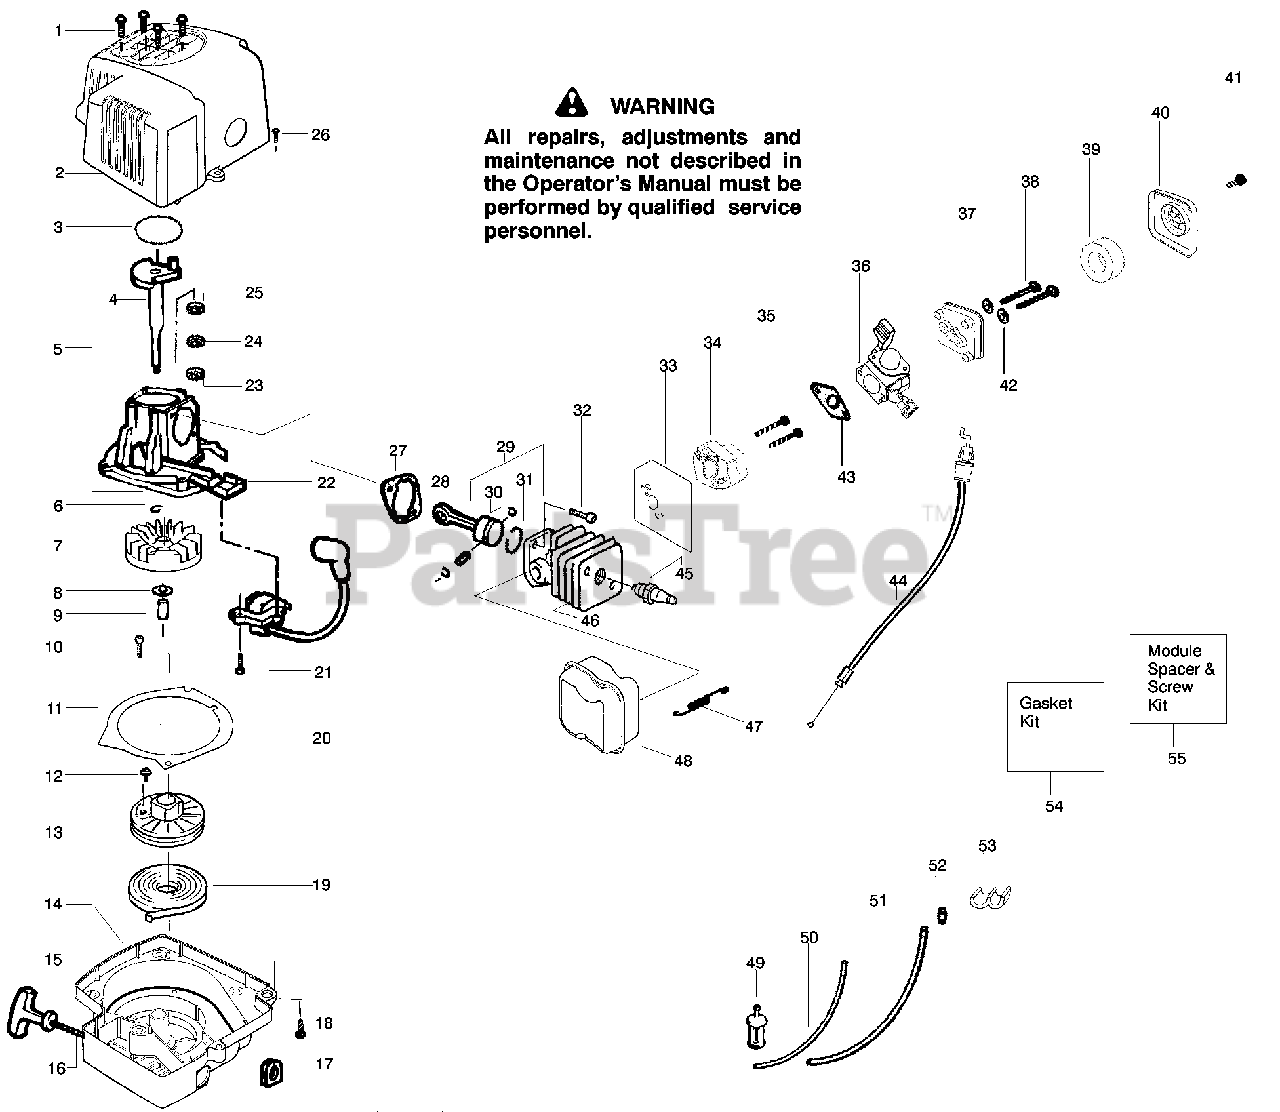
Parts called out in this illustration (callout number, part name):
2	Assy-Shroud
3	O-Ring-Shrd (kit)
4	Assy-Crankshaft
5	Assy-C/case-C/shaft
6	Ring-Retainer-C'shaft
7	Assy-Flywheel
8	Washer-Flat
9	Spacer-Flywheel
11	Plate-Baffle
13	Kit-Starter Pulley
14	Assy-Fan Housing
15	Handle-Starter
16	Kit-Rope
17	Grommet-Ignition Module
18	Screw-(f/hsg to shrd)
19	Spring-Starter
21	Ignition Module GHT 180/220
21	Ignition Module GHT 220 CAN.
22	Assy-Crankcase
23	Bearing-Outer
24	Kit-Crankcase Seal
25	Bearing-Inner
27	Gasket-Cylinder (kit)
28	Assy-Connecting Rod
29	Kit-Piston
30	Retainer-Piston Pin
31	Ring-Piston
33	Gasket-Carb. Adapt.(kit)
34	Adapter-Carburetor
36	Kit-Carburetor Ass'y. (C1U-W13A)
39	Air Filter Foam
40	Air Filter Cover
42	Washer
43	Gasket-Carburetor (kit)
44	Assy-Throttle Cable
45	Spark Plug(RCJ-6Y)
46	Kit-Cylinder
47	Spring-Muffler
48	Kit-Spark Muffler
49	Assy-Pick-up
50	Kit-Fuel Line (small)
51	Kit-Fuel Line (large)
52	Fitting-Fuel Line
53	Clip-Retainer
54	Kit-Gasket
55	Kit-Module Spacer & Screws
